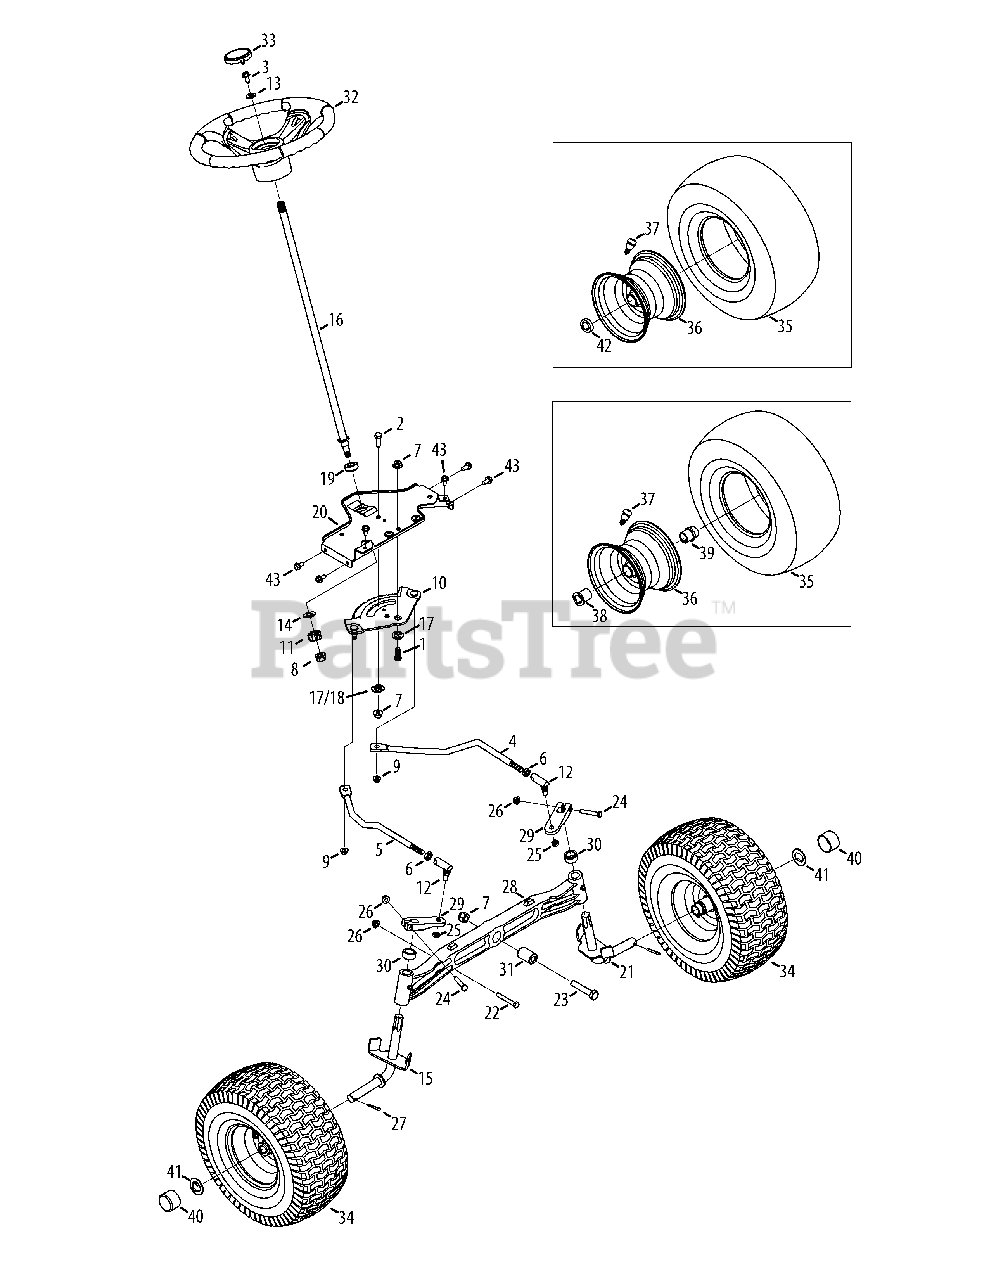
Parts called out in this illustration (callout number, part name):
1	Hex Screw, 3/8-16x1.00, Gr5, Special
2	Hex Screw, 3/8-16x1.00, Gr5, Std
3	Hex Screw, 5/16-18x1.00, Gr5, Lock
4	Link, Drag LH
5	Link, Drag RH
6	Nut, Jam, 7/16-20, Gr2
7	Nut, Flange Lock, 3/8-16
8	Nut, Flange Lock, 7/16-20, Grb, Lock
9	Nut, Flange Lock, 5/16-18, Gr5, Sd Lk
10	Gear, Steering
11	Gear, Pinion, Steering
12	Ball Joint, 7/16-20, Lock
13	Washer, Flat, .406 x .875 x .105
14	Washer, Flat, .51 x 1.12 x .06
15	Axle Ass’y, RH .750 Dia
16	Shaft, Steering, .625 OD x 24.25
17	Spacer, Shoulder, .385x 1.25 x .3025
18	Spacer, .38 x 1.375, Special
19	Bearing, Flange, Hex 5/8
20	Bracket, Support, Steering
21	Axle Ass’y, LH .750 Dia
22	Hex Screw, 5/16-18, 2.25, Gr5, Std
23	Hex Screw, 3/8-16, 2.50, Gr5, Std
24	Hex Screw, 5/16-18, 1.75, Gr5, Std
25	Nut, Hex Lock, 3/8-24, Grb
26	Nut, Flange Lock, 5/16-18
27	Pin, Cotter, 5/32, 1.25
28	Axle, Pivot Bar, Cast
29	Steering, Block
30	Spacer, .71 ID x .125 OD x .56
31	Spacer, .385 x 1.00 x 1.5075
32	Steering Wheel, Standard Grip
33	Cap, Sprig, Small
34	Wheel Assembly
35	Tire, 15 x 6 x 6
36	Rim Assembly
37	Tubeless Air Valve
38	Flange Bearing, .760 x 1.00 x 1.20
39	Flange Bearing, .760 ID
40	Cap, Bumper
41	Washer, Flat, .350 x 1.559 x .062
42	Bearing, Ball, .750 x 1.750
43	Screw, Self-tapping, 5/16-18, .750
